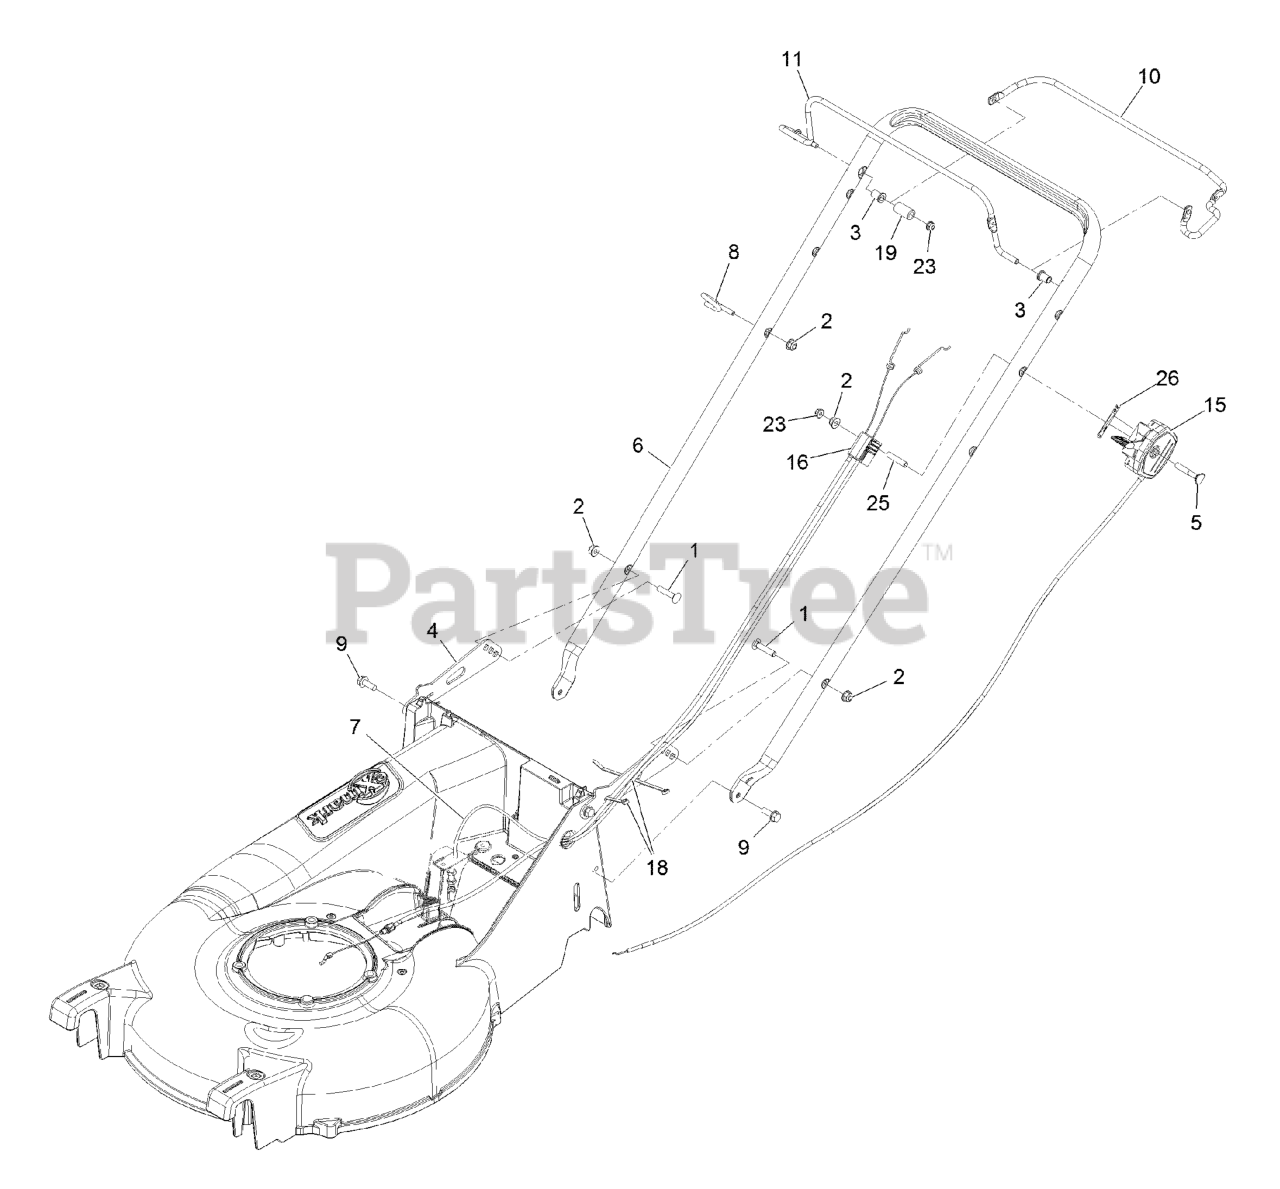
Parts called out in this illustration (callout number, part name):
1	BOLT-CARR
2	NUT-HF, NI
3	BUSHING-HANDLEBAR
4	BRACKET,HANDLEBAR
5	SCREW-HH
6	HANDLEBAR-P21
7	CABLE, DRIVE EC21
8	GUIDE,ROPE
9	SCREW-TAPTITE
10	BAIL-DRIVE COATED
15	CABLE-THROTTLE/CHOKE
16	CABLE-ZONE HONDA
18	TIE-CABLE
25	SPACER-THROTTLE
26	DECAL,THROTTLE/CHOKE
